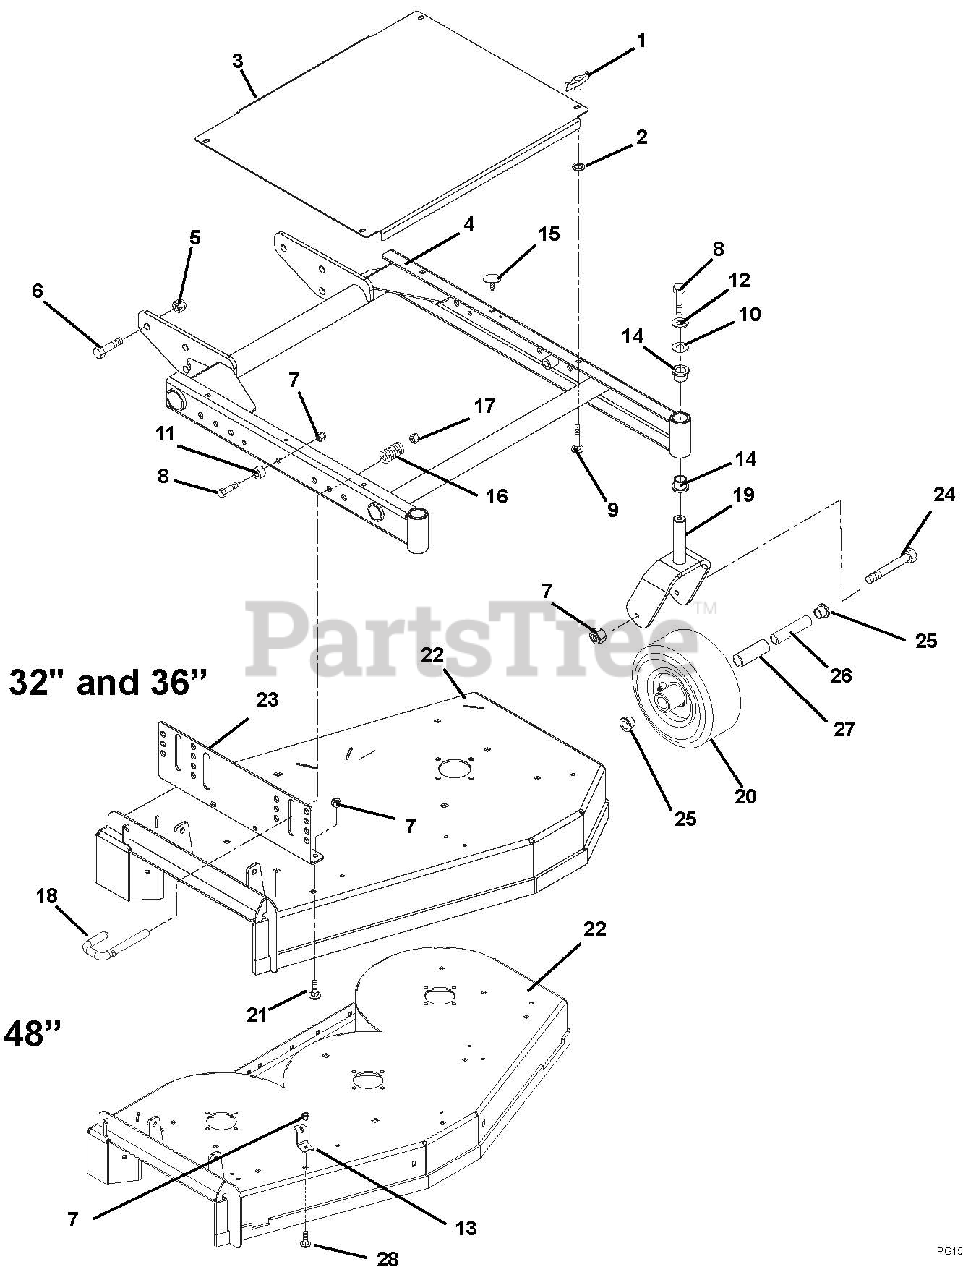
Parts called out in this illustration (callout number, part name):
1	Knob- Wing .312-18
2	Nut, Push .312
3	Cover, Belt Pro Mower
3	Cover, Belt Pro Mower - 32"
4	Weldment - Mower Frame 36"
4	Weldment - Mower Frame 48"
4	Weldment - Mower Frame 32"
5	Nut, Locking-Nylon .625-11
6	Bolt, Hex .62-11 x 1.50
7	Nut, Locking-Top-Flange .38-16
8	Bolt, Hex .38-16 x 1.25 Grade 5
9	Bolt, Round Head Square Neck .31-18 x 1.00
10	Washer, Flat-Steel .38 x 1.50 x .125
12	Washer, Locking .38 x .094 Regular
13	Anchor, Spring
14	Bushing-Flange 1.00 x 1.25 x 1.50 x 1.50
15	Bumper Grommet .125 x .25 Dia.
16	Spring-Compression .058 x .65 x 2.13
17	Nut, Locking-Center .50-13
18	Pin- Latch
19	Weldment-Caster Fork
20	Wheel 9 x 3.50
21	Bolt, Round Head Square Neck .38-16 x 1.00 Grade
22	Kit, 32" Fixed Mower Deck with Decals
22	Kit, 36" Fixed Mower Deck with Decals
22	Kit, 48" Fixed Mower Deck with Decals
23	Kit-Mower Side Support Bracket-Right Hand and Left Hand
24	Bolt, Hex .38-16 x 5.50
25	Bearing-Retainer
26	Bearing .625 x .380 x 4.08
27	Bearing-Roller
28	Bolt, Round Head Square Neck .38-16 x .75 Grade 5
